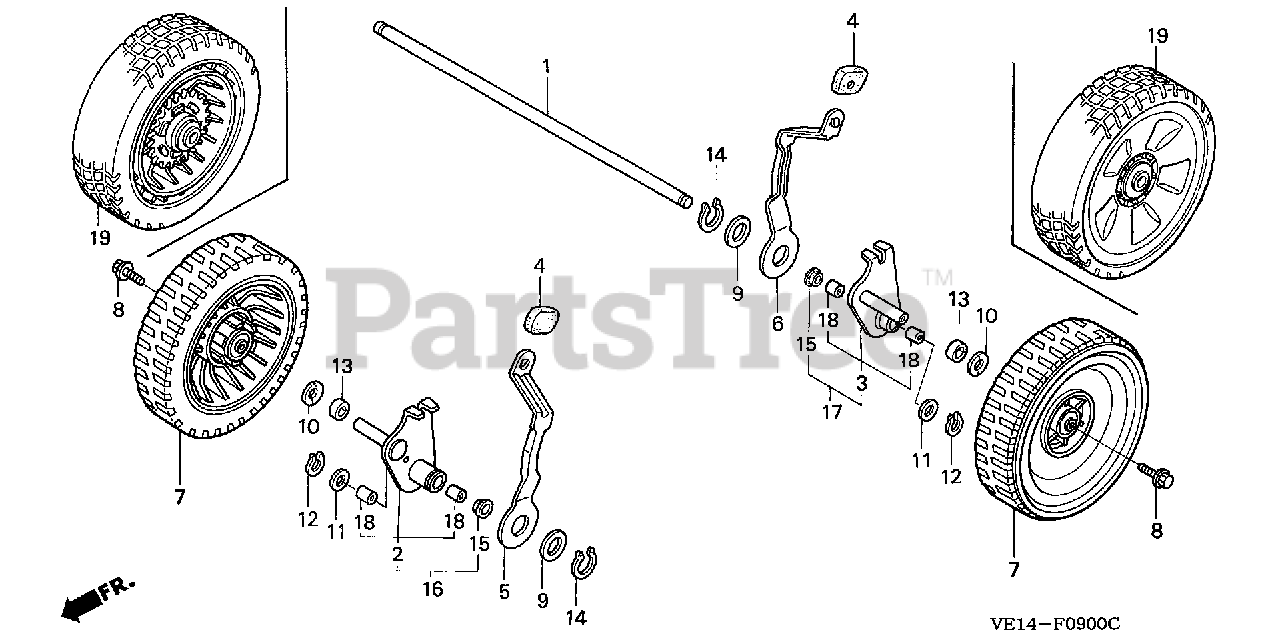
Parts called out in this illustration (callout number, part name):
1	SHAFT, WHEEL
2	ARM, R. RR. ADJUSTING
3	ARM, L. RR. ADJUSTING
4	GRIP, ADJUSTER
5	PLATE, R. RR. ADJUSTER
6	PLATE, L. RR. ADJUSTER
7	WHEEL, FR. (PART DESCRIPTION SAYS "FR." BUT IT IS ALSO USED FOR REAR)
8	BOLT, WHEEL
9	WASHER, PLAIN (22MM)
10	WASHER, WHEEL
11	WASHER, THRUST (13MM)
12	CIRCLIP (OUTER) (12.7MM)
13	COLLAR, WHEEL
14	CIRCLIP (OUTER) (22MM)
